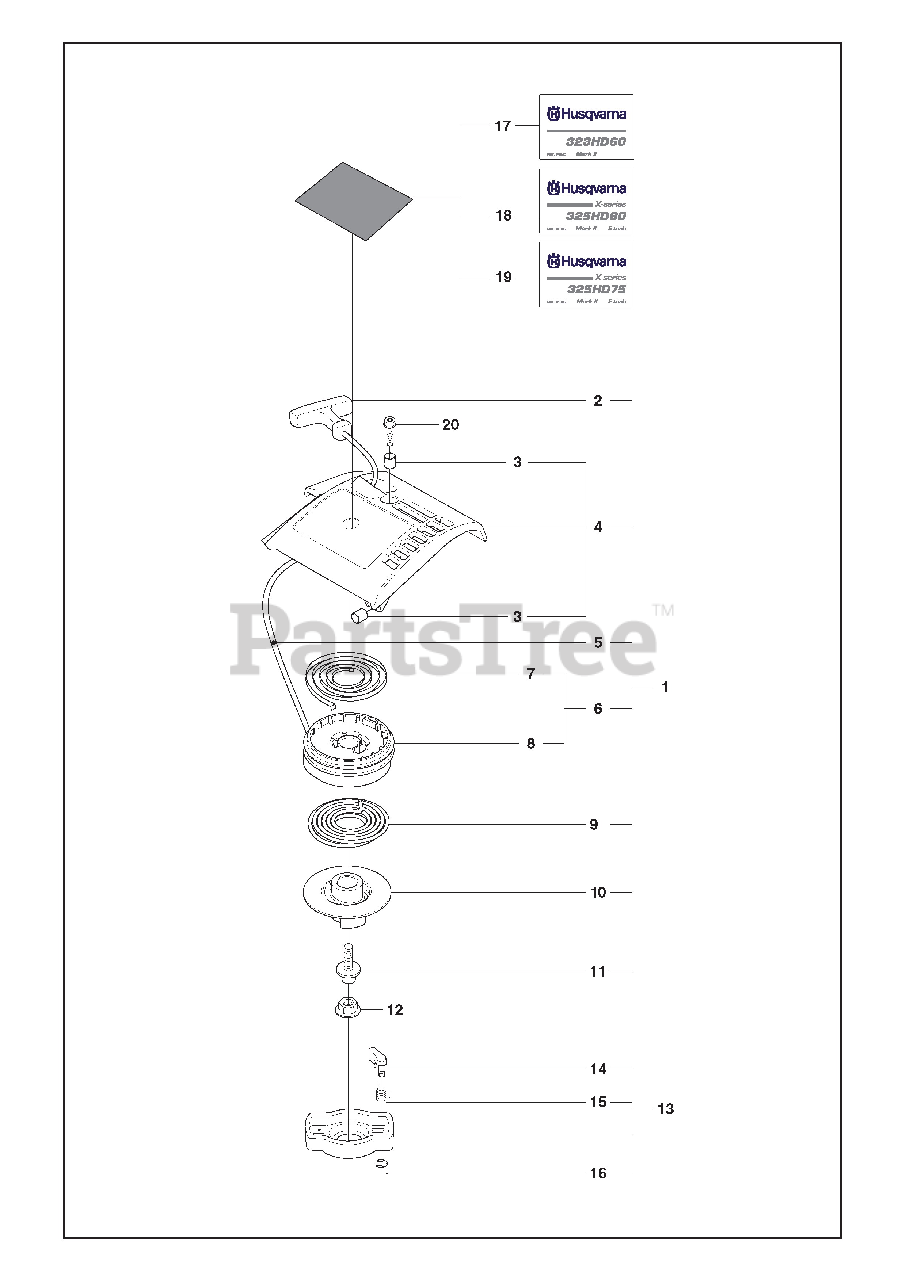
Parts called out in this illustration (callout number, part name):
1	RP STARTER ASSY
2	STARTER HANDLE
3	STARTER HOUSING
4	STARTER ROPE
5	STARTER PULLEY
7	STARTER PULLEY
8	SPRING - DRIVER
9	DRIVER PULLEY
11	FLANGE NUT
12	PAWL ASSY COMPLETE
13	SPACING SLEEVE
14	STARTER PAWL
